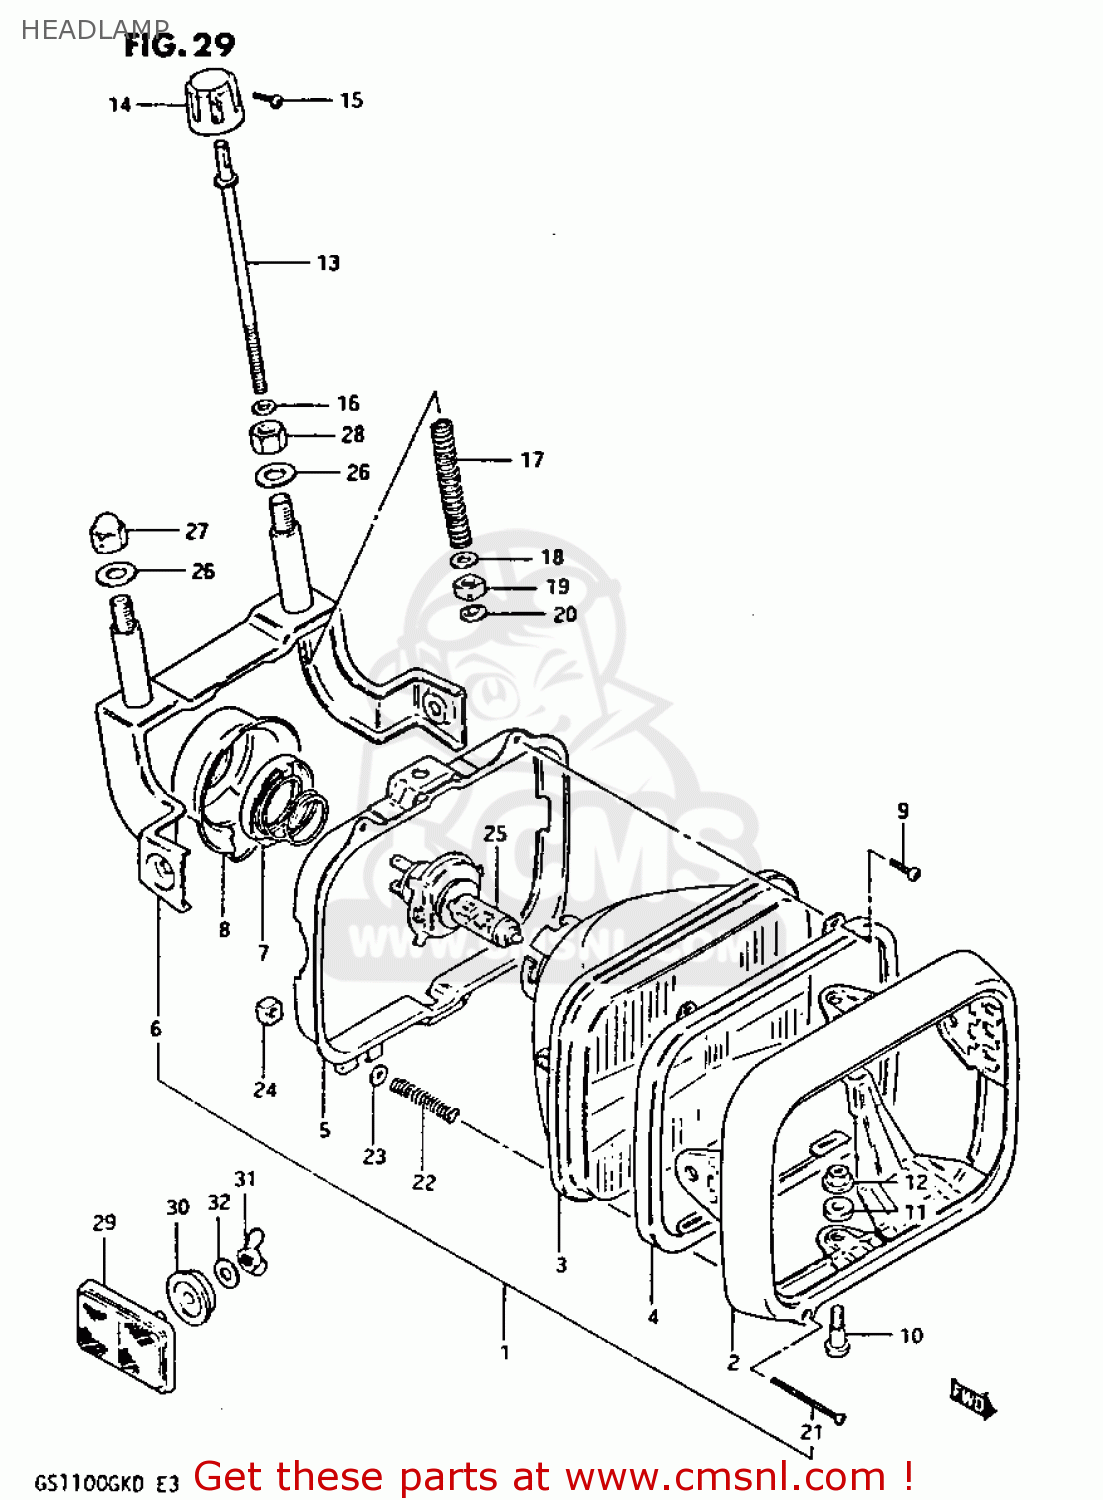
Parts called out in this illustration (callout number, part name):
1	HEADLAMP ASSEMBLY
2	RIM,HEADLAMP
3	LAMP UNIT
4	RETAINER,HEADLAMP
5	RING,MOUNTING
6	HOUSING
7	HOLDER
8	COVER,HEADLAMP SOCKET
9	SCREW
10	SCREW
11	SPACER
12	NUT,ADJUSTING
13	SCREW,HEADLAMP ADJUST
14	KNOB,ADJUSTER
15	SCREW 3X12
16	WASHER
17	SPRING,HEADLAMP ADJUST
18	WASHER
19	SPACER
20	NUT,HEADLAMP ADJUSTER
21	SCREW,HEADLAMP ADJUST
22	SPRING,HEADLAMP ADJUST
23	WASHER
24	NUT
25	BULB(12V60/55W,H4)
26	WASHER
27	NUT
28	NUT
29	REFLECTOR,REFLEX
30	SPACER,FRONT REFLEX REFLECTOR
31	NUT, WING
32	WASHER
